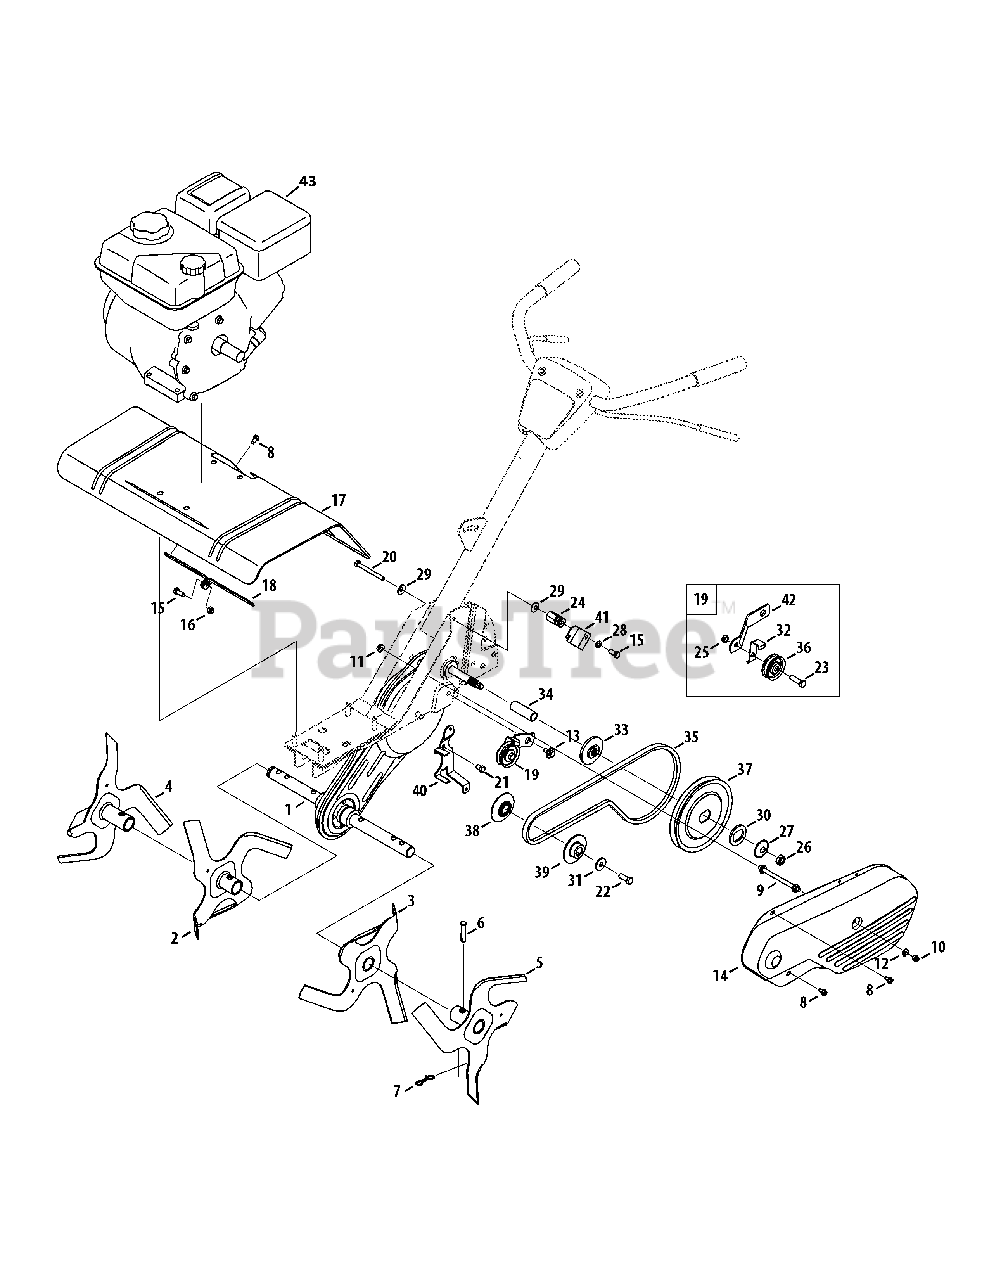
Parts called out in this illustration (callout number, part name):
1	Chain Case Assembly
2	RH Inner Tine Assembly
3	LH Inner Tine Assembly
4	RH Outer Tine Assembly
5	LH Outer Tine Assembly
6	Clevis Pin, .375 x 1.75
7	Bow Tie Cotter Pin
8	Screw, 1/4-20 x 0.500
9	Belt Cover Bolt
10	Lock Nut, 1/4-20
11	Flange Lock Nut, 5/16-18
12	Flat Washer, .271 x .630 x .065
13	Shoulder Screw, 5/16-18 x .560 x .165
14	Belt Cover
15	Hex Screw, 5/16-18 x .75
16	Flange Lock Nut, 5/16-18
17	Tine Shield
18	Tine Shield Bracket
19	Idler Bracket Assembly
20	Hex Screw, 5/16-18 x 3.00
21	Hex Screw, 5/16-24 x .625
22	Hex Screw, 3/8-24 x 1.00
23	Hex Screw, 3/8-16 x 1.25
24	Hex Nut, 5/16-18
25	Jam Nut, 3/8-16
26	Jam Nut, 1/2-20
27	Washer, .531 x 1.62 x .045
28	Lock Washer, 5/16
29	Bell Washer, .340 x .872 x .060
30	Flat Washer, 1.26 x 1.87 x .150
31	Bell Washer, .396 x 1.140 x .095
32	Belt Keeper
33	Pulley Adaptor
34	Spacer, .64 x 2.4
36	Pulley, 1.88
37	Pulley, 6.00
38	Inner Engine Pulley
39	Outer Engine Pulley
40	Belt Keeper Bracket
41	Cable Guide Bracket
42	Idler Bracket
